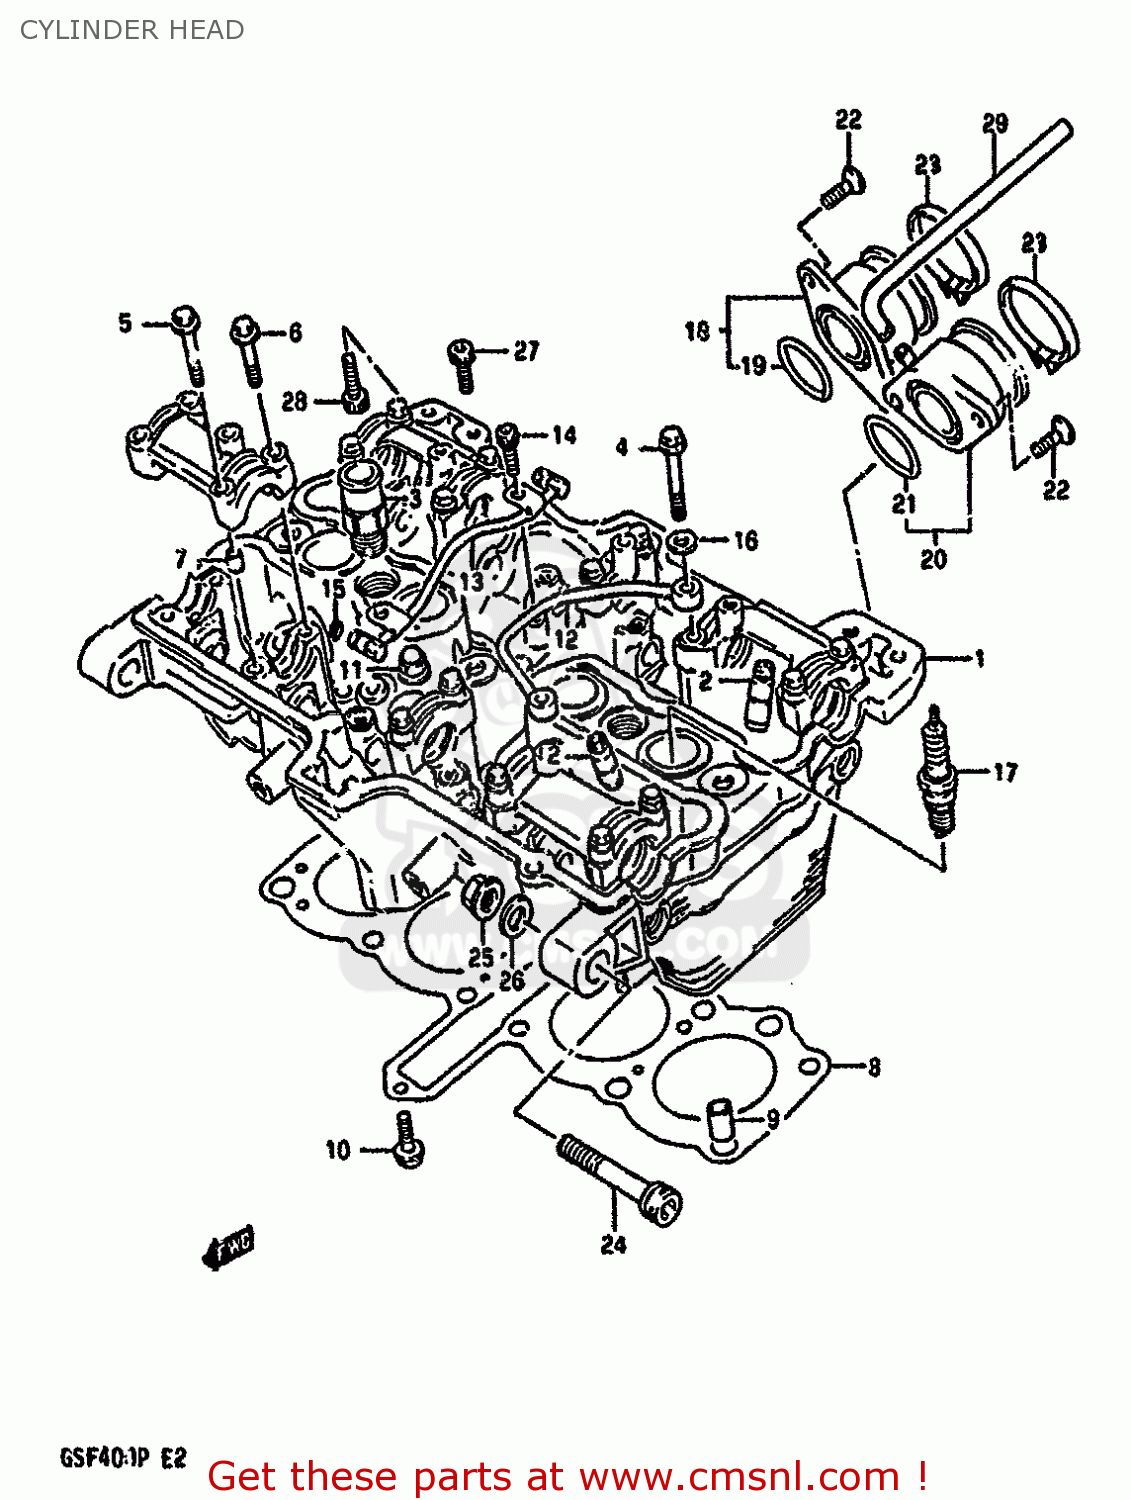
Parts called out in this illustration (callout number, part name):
1	HEAD ASSEMBLY,CYLINDER
2	GUIDE,VALVE
3	UNION,WATER HOSE
4	BOLT
5	BOLT(6X39)
6	BOLT(6X35)
7	PIN(6.2X8X11)
8	GASKET,CYLINDER HEAD (NAS)
9	PIN
10	BOLT
11	NUT 8MM
12	PIPE,OIL CYLINDER HEAD,L
13	PIPE,OIL CYLINDER HEAD
14	BOLT,STRANGER
15	O RING(D:1.9,ID:4.8)
16	WASHER, LOWER
17	PLUG,SPARK(CR9EK)
18	PIPE ASSY,INTAKE
19	O-RING
20	PIPE ASSY,INTAKE NO.2
21	O-RING
22	SCREW(6X16)
23	CLAMP
24	BOLT
25	NUT (10MM)
26	WASHER(10.5X20X3.2)
27	BOLT
28	BOLT
29	HOSE
